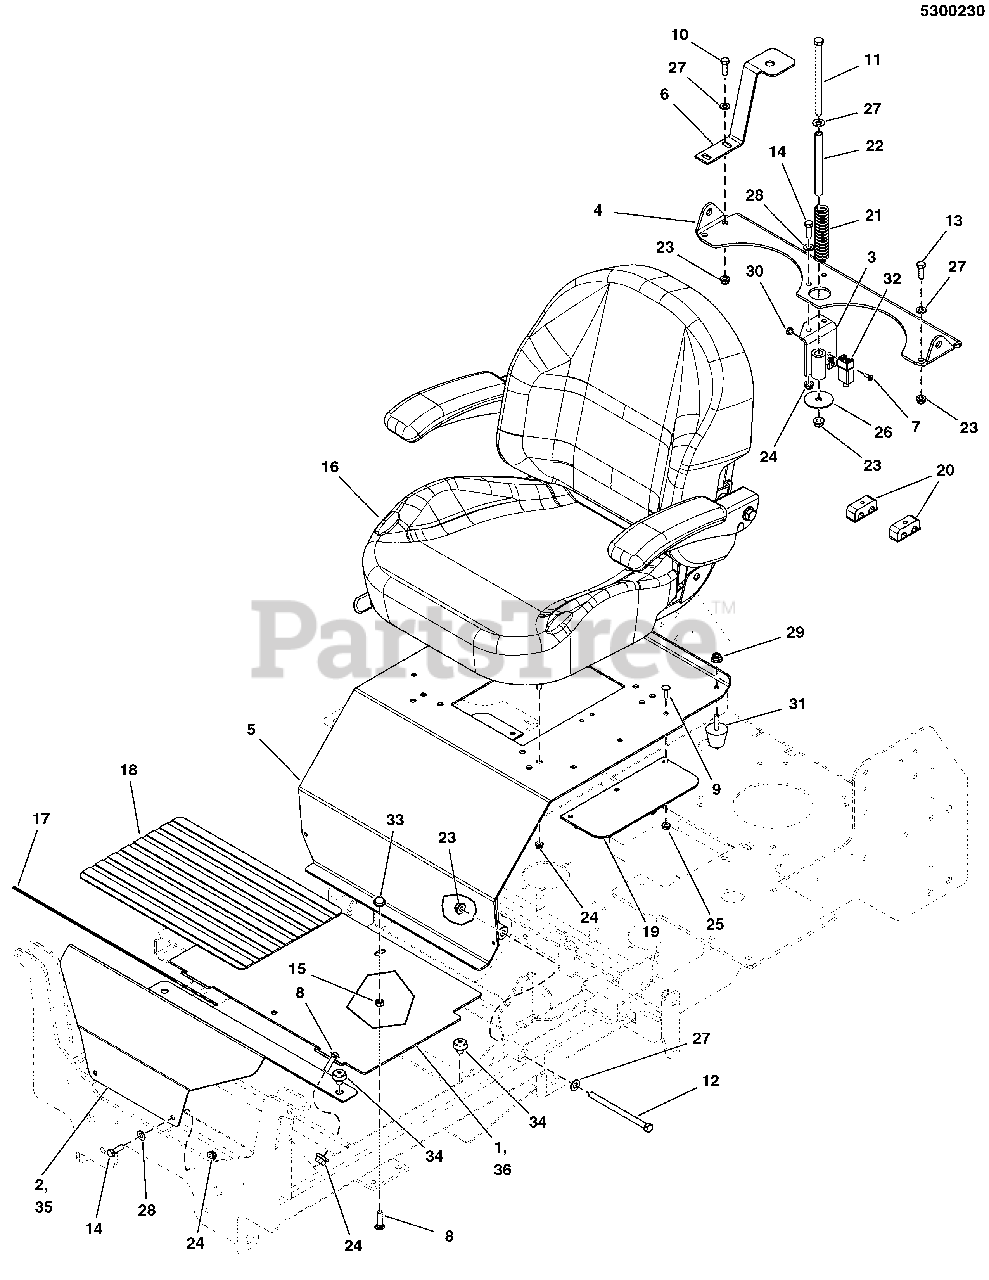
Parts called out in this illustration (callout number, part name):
1	PLATE, FLOOR REMOVABLE, COBALT - ORG
2	PLATE, FRONT FLOOR, COBALT - ORG
3	WELD, BRACKET, SPRING SWITCH - ORG
4	PLATE,SEAT SUPPORT - ORG
5	WELD, SEAT PLATE - COBALT - ORG
6	BRACKET, FUEL VALVE, COBALT - BLK
7	SCREW, #10-24 X 3/4 ROUND PHILLIPS
8	BOLT, 5/16-18 X 1, CARRIAGE YZ
9	BOLT, 1/4-20X.750, SQ
10	BOLT, 3/8-16 X 1 GD5 YZ
11	BOLT, 3/8-16 X 6 GD5 YZ
12	BOLT, 3/8-16 X 5-1/2 GD5 YZ
13	BOLT, 3/8-16 X 1-1/4 GD5
14	BOLT, 5/16-18 X 1 GD5 YZ
15	NUT, 5/16-18, GRB, HEX, CNTR LK, ZINC/CL [80003675]
16	SEAT, 2012
17	SAFETY WALK, FLOOR REST, 6.00 X 16.00
18	SAFETY WALK, FLOOR PLATE, S50X, 10X16
19	PLATE, SEAT, RUBBER FLAP
20	CLAMP, 1/2" HOSE, DOUBLE, PLASTIC
21	SPRING, .688 ID X .130 WIRE DIA 4.25
22	SPACER, .38 X .50 X 5.06
23	NUT, 3/8-16 HEX NYLOCK FLANGE
24	NUT, 5/16-18 HEX NYLOCK FLANGE
25	NUT, 1/4-20 HEX NYLOCK FLANGE (5025391)
26	WASHER, .39 X 2.00 X X .14
27	WASHER, 3/8 SAE
28	WASHER, 5/16 SAE
29	NUT, 5/16-18 HEX SERRATED FLANGE (SMALL)
30	NUT, #10-24 HEX
31	BUMPER, RUBBER 5/16-18
32	SWITCH, PLUNGER, N.C./N.C.
33	ACORN NUT, 5/16-18 S/S
34	MNT, VBRTN, RBBR
35	PLATE, FRONT FLOOR, COBALT - ORG
36	PLATE, FLOOR REMOVABLE, COBALT - ORG
